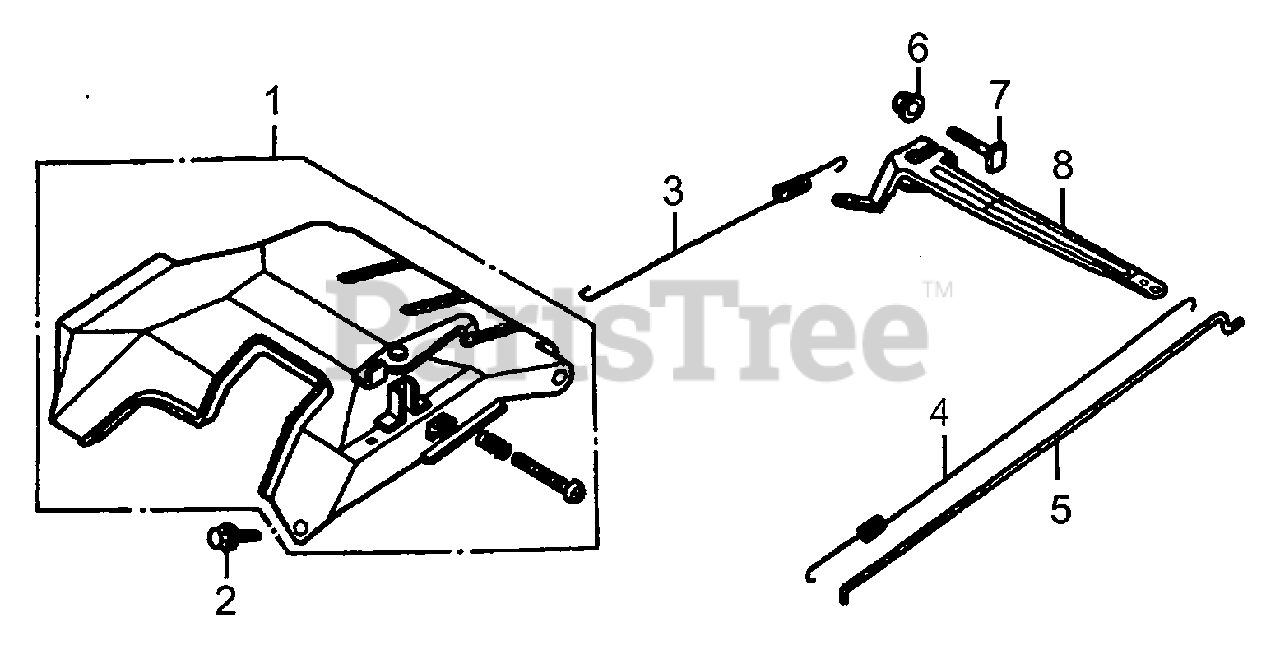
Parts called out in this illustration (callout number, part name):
1	CONTROL ASSY.
2	BOLT' FLANGE' 6×12
3	SPRING' GOVERNOR A
4	SPRING' GOVERNOR B
5	ROD' GOVERNOR
6	NUT' FLANGE' M6
7	BOLT' GOVERNOR ARM
8	ARM' GOVERNOR
